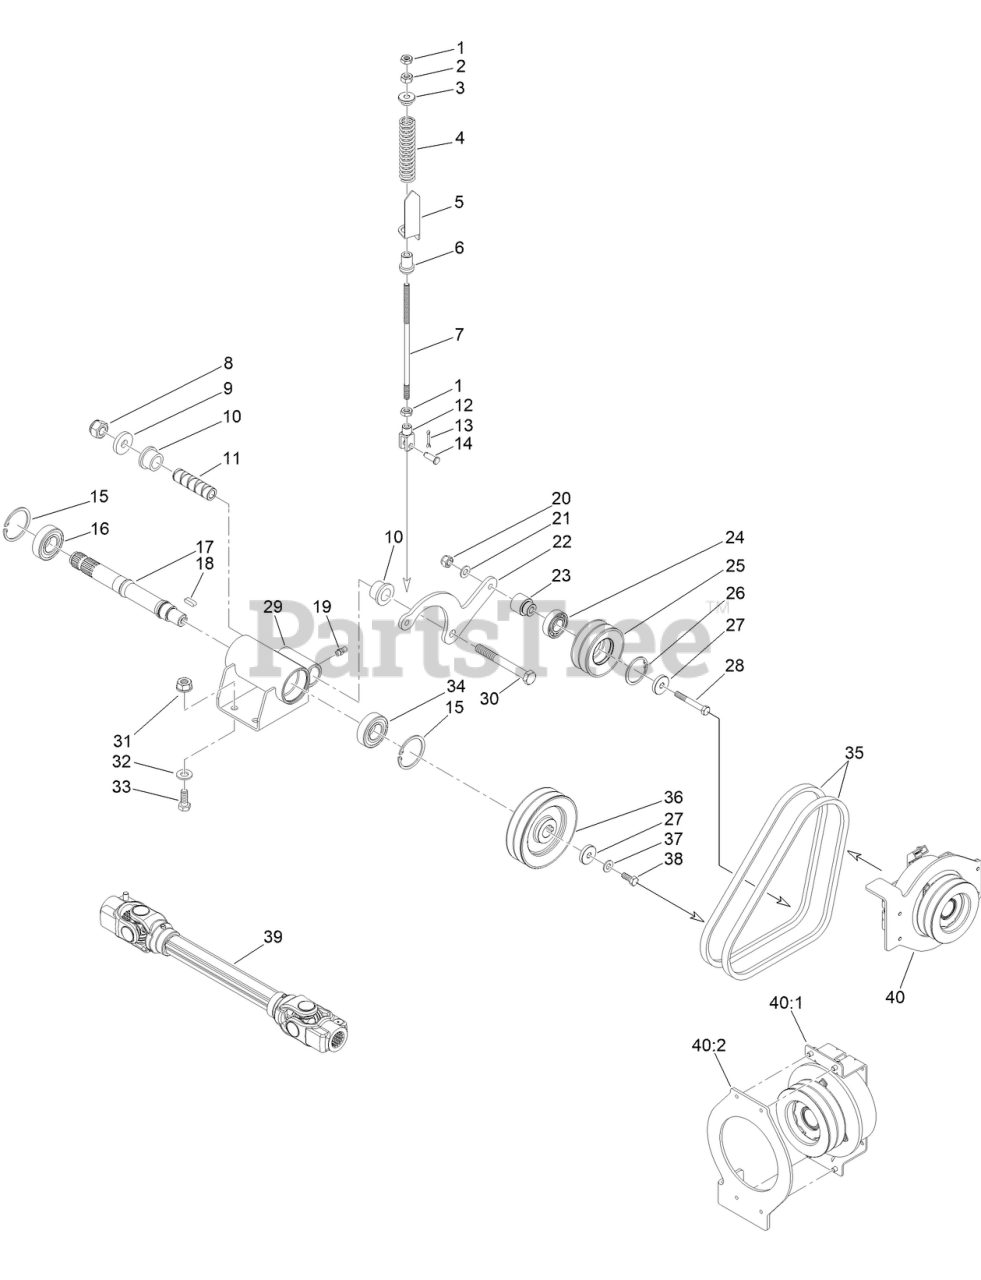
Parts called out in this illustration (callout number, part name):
3	GUIDE-SPRING
4	SPRING-EXTENSION
5	INDICATOR, PTO BELT TENSIONER
6	PIN-GUIDE, NYLON
7	ROD, PTO BELT TENSIONER
9	WASHER
10	BUSHING
11	SPACER
12	FORK-CLEVIS, M8
13	PIN-SPRING
15	RING-RETAINING, INT
16	BEARING
17	SHAFT, PTO
19	FITTING-GREASE
21	WASHER
22	BRACKET, PTO BELT TENSIONER
23	BUSHING
24	BEARING
25	PULLEY, PTO BELT TENSIONER
26	RING-RETAINING, INT
27	WASHER
29	HUB, PTO
32	WASHER
34	BEARING
35	BELT, PTO
36	PULLEY, PTO SHAFT
37	WASHER
39	SHAFT, CARDAN JOINT
40	CLUTCH ASSY
40:1	CLUTCH, GT1.5-GR15D
40:2	BRAKE, CLUTCH
